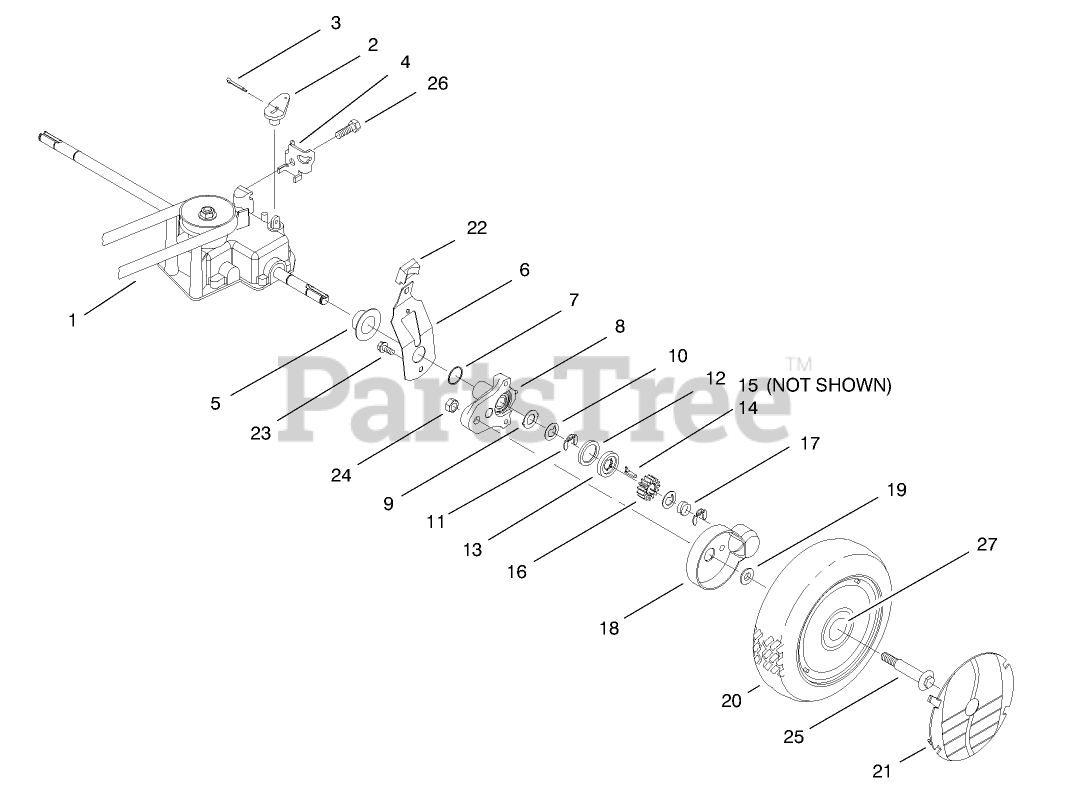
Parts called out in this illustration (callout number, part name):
1	V-BELT
2	LEVER-SHIFT
3	PIN-COTTER
4	CLAMP-CABLE
5	CAP-END
6	SPRING ARM ASM
7	O-RING
8	PIVOT ARM ASM
9	WASHER-ARM, PIVOT
10	WASHER-THRUST, KEYED
11	RING-RETAINING,CLIP
12	RING-FRICTION
13	WASHER-CLUTCH
14	KEY-ROCKING, LH
15	KEY-ROCKING, RH
16	GEAR-PINION
17	SPRING-COMPRESSION
18	COVER-WHEEL
19	SPACER-COVER, WHEEL
20	WHL & TIRE ASSEMBLY
22	KNOB-ARM
23	SCREW-HWH
24	NUT-LOCK
26	SCREW-HWHTF
27	BUSHING
